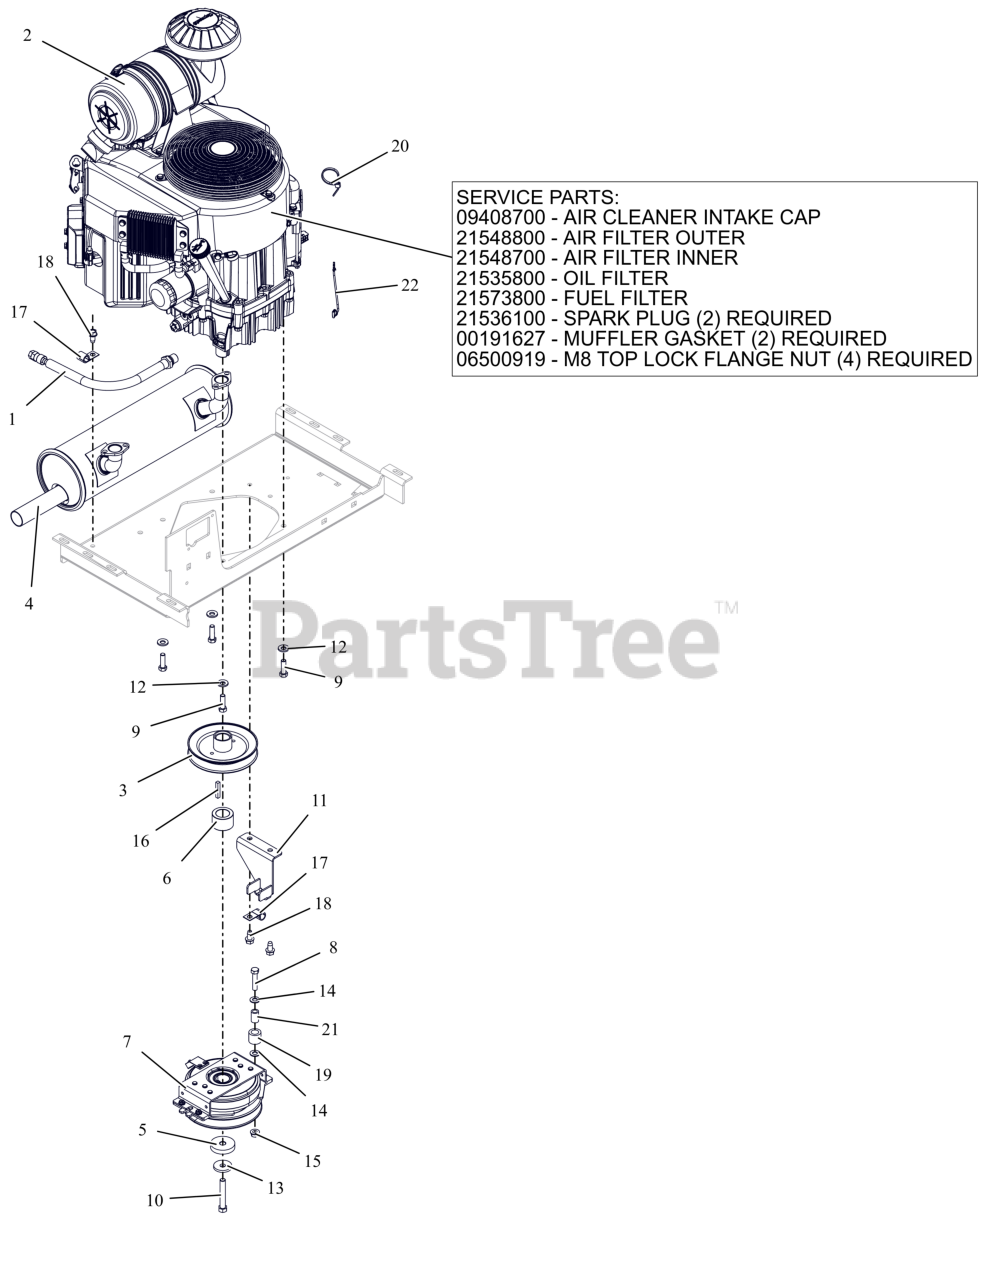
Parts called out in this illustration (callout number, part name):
1	HOSE, OIL DRAIN
2	ENGINE, KAWASAKI FX801
2	CAP, AIR CLEANER INTAKE (2")
2	FILTER, OUTER
2	FILTER, INNER - KAW
2	FILTER,OIL - KAW
2	FUEL FILTER
2	PLUG, SPARK
2	GASKET, MUFFLER S/O
2	NUT-LK-TOP-FLG M8 ZCC
3	WLDMT, TRANSAXLE DRIVE PULLEY
4	MUFFLER, KAWASAKI FX850
5	SPACER, .450X2.00X.396
6	SPCR, 1.125 x 1.750 x 1.147
7	CLUTCH- OGURA GT2.75-DC03(D)
8	BLT, HEX .38-16X1.75 G5 ZCC
9	BLT, HEX .38-16X1.25 G5 ZCC NT
10	BLT, HEX 0.4375-20X2.75 G8 ZCC NT
11	BRKT, CLUTCH STOP
12	WASHER, 3/8" SPRING DISC
13	WASHER, 7/16" SPRING DISK
14	WSHR,FLT .406X.812X.065 ZCC
15	NUT-LK-CTR-FLG .375-16 GF ZCC
16	KEY-SQ .25 X 1.50 X .25 SAE
18	SCR,TAP .375-16X.75 HWH TR ZCC
19	BUMPER,RUBBER .62X1.0X.88 LG
20	CABLE TIE LG 5-1/2
21	BUSH.,S.391X.622X.950 ST
22	LEAD - STARTER SOLENOID
